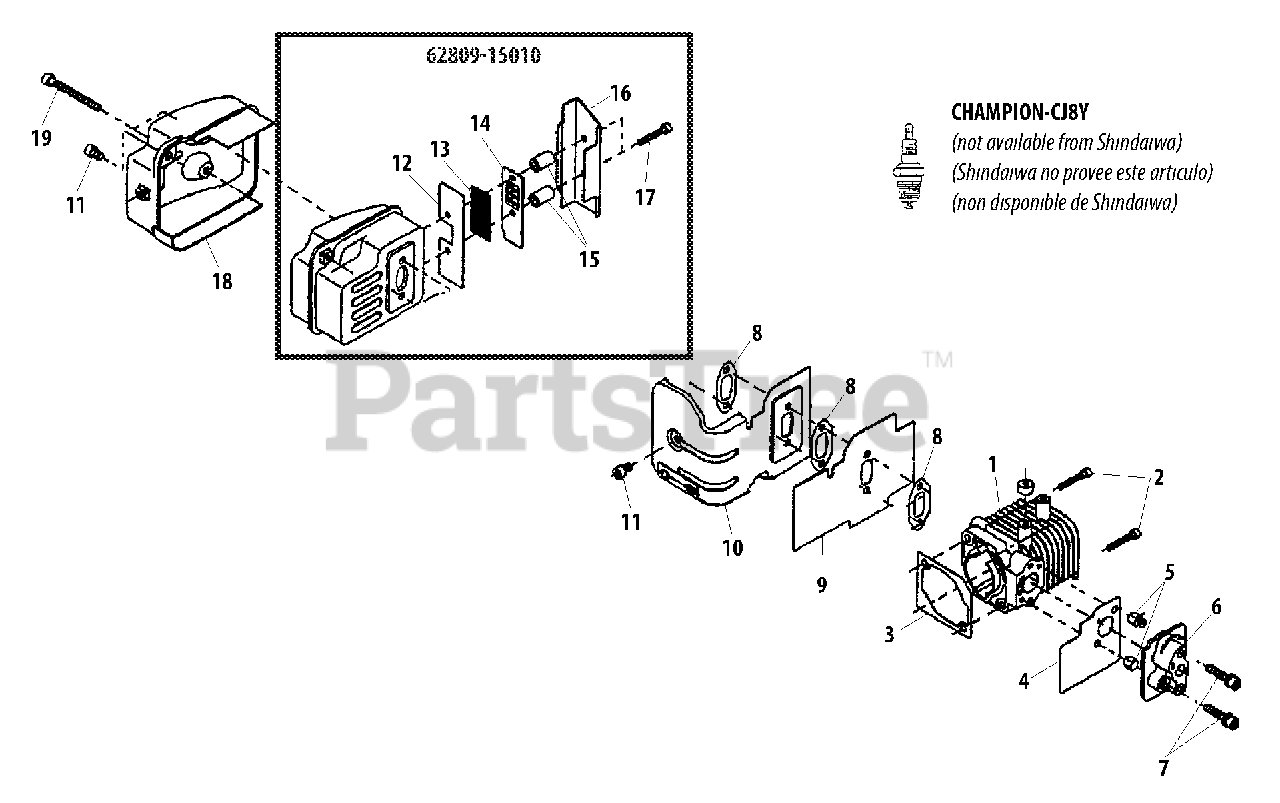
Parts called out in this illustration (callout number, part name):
1	CYLINDER
2	SCREW - 5X25
3	GASKET, CYLINDER
4	SHIELD, INTAKE
5	NUT
6	INSULATOR
7	SCREW - 5X30
8	SHIELD, EXHAUST
9	SHIELD, EXHAUST
10	GASKET, EXHAUST
11	SCREW - 5X8
12	PLATE
13	SCREEN, SPARK ARRESTOR
14	TAIL PLATE
15	SPACER
16	DEFLECTOR
17	SCREW - 4X25
18	COVER, EXHAUST
19	SCREW - 5X65
62809-15010	MUFFLER ASSY
